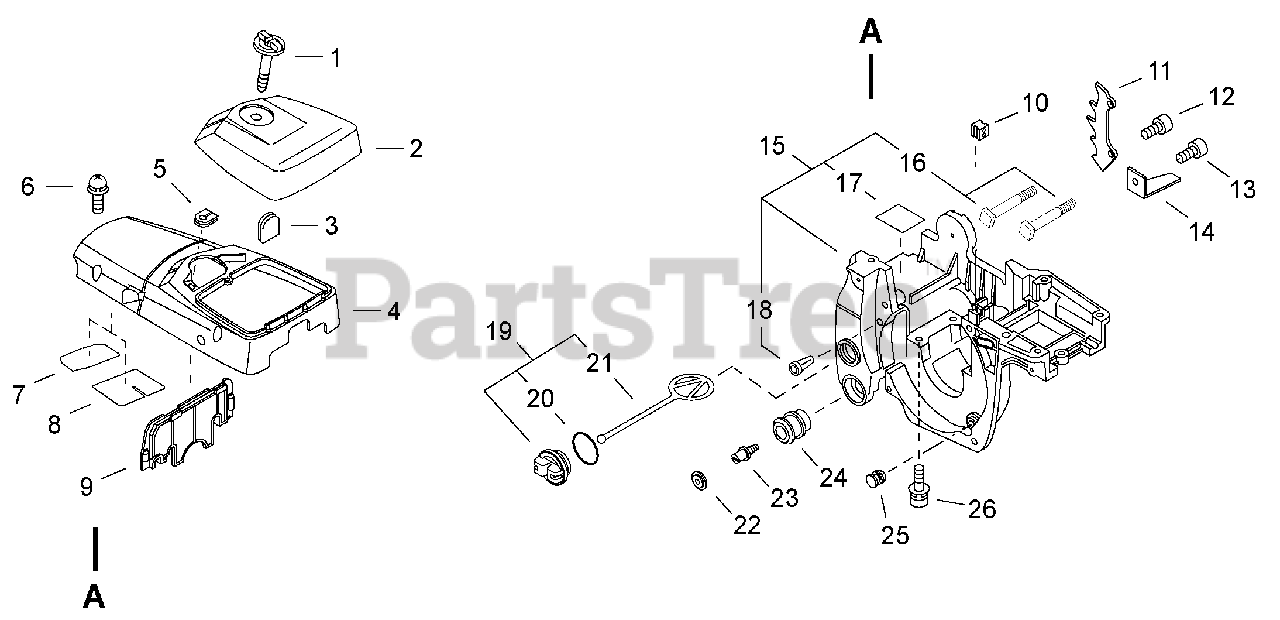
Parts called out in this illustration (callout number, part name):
1	THUMBSCREW
2	COVER, AIR FILTER
4	COVER, ENGINE
5	GROMMET
6	SCREW 5×20
7	SHIELD, HEAT
8	SHIELD, HEAT
9	PLATE, INSULATOR
10	GROMMET, LEAD
11	SPIKE, BUMPER
12	SCREW TAPPING 5×20
13	SCREW TAPPING 5×16
14	CHAIN CATCHER
15	COVER ASSY, ENGINE
16	STUD, GUIDE BAR 8
17	SHIELD, HEAT
18	VENT ASSY
19	CAP ASSY
20	O-RING 25
21	CONNECTOR, CAP L= 60 MM
22	CAP, CUSHION
24	CUSHION 5
25	CUSHION
26	BOLT 5×30
